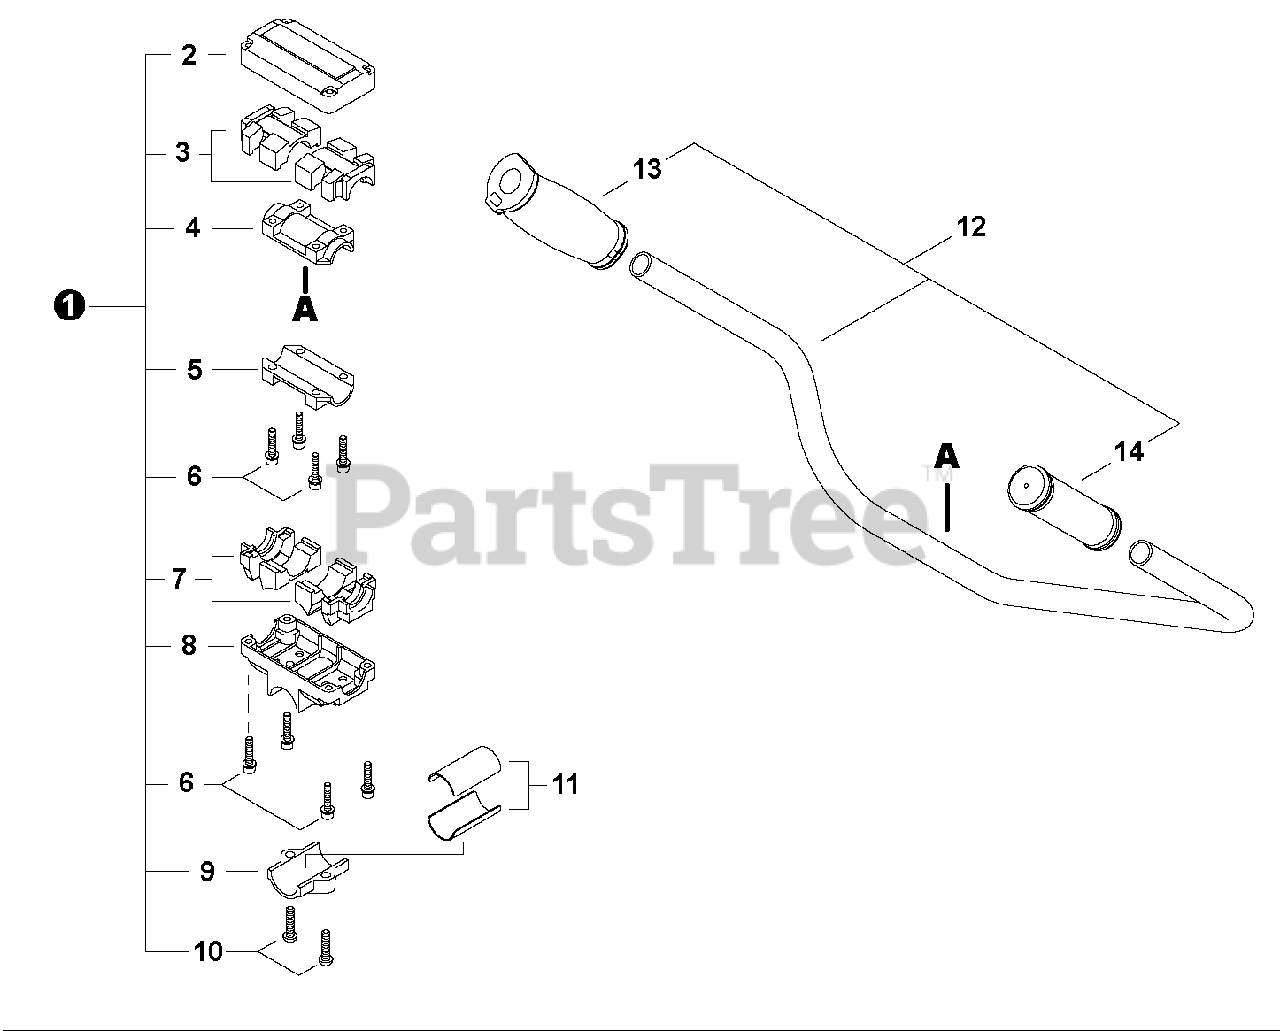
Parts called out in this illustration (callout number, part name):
1	Bracket Assy, Handle
2	Clamp, Upper
3	Cushion, Upper
4	Clamp, Upper
5	Clamp, Lower
6	Bolt M5x25
7	Cushion, Lower
8	Bracket, Handle dia.28
9	Clamp, Lower dia.28
10	Screw M6x25
12	Handle Assy
13	Grip, Right
14	Grip, Left
